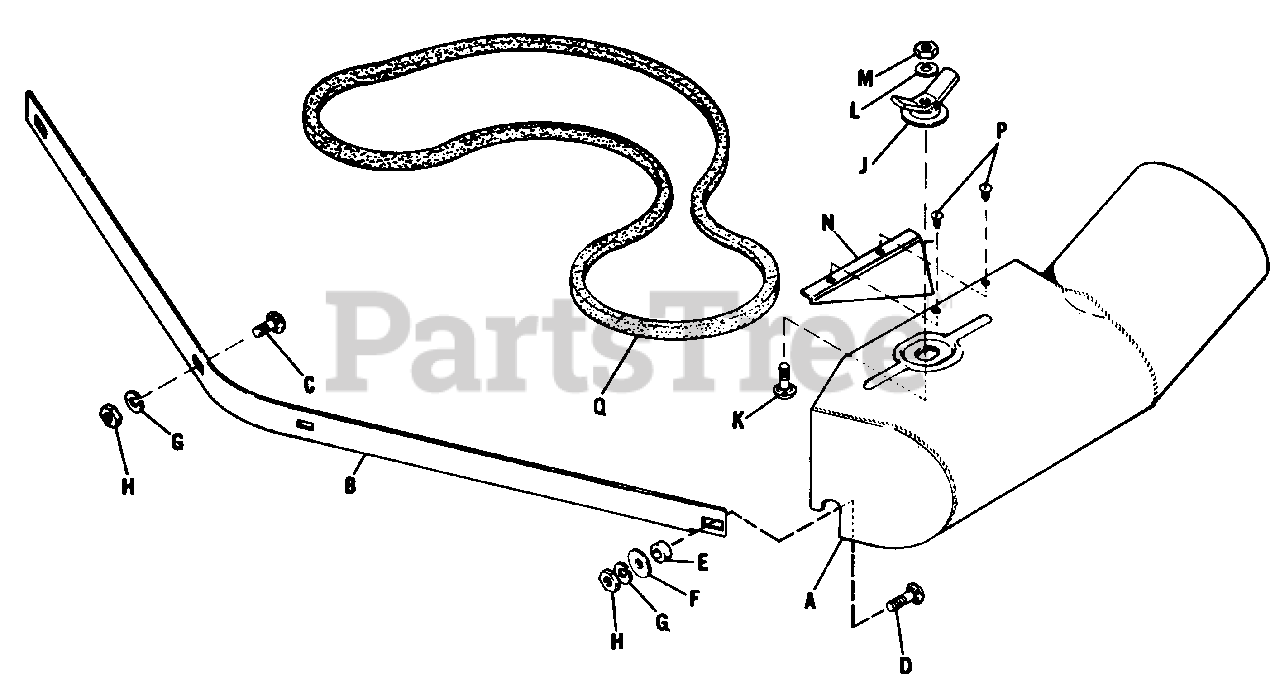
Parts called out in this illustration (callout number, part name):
A	Collector Side Housing Assembly
B	Front Baffle
C	Carriage Bolt, 3/8"-16 x 1" lg.
D	Carriage Bolt, 3/8"-16 x 1-1/4" lg.
G	Lock Washer, 3/8"
H	Nut, Hex, Full, 3/8"-16
J	Nut Assembly
K	Carriage Bolt, 3/8"-16 x 1" lg.
L	Lock Washer, 3/8"
M	Nut, Hex, Full, 3/8"-16
P	Screw, Self Tapping, No. 10-24 x 1/2" lg.
Q	"V" Belt
